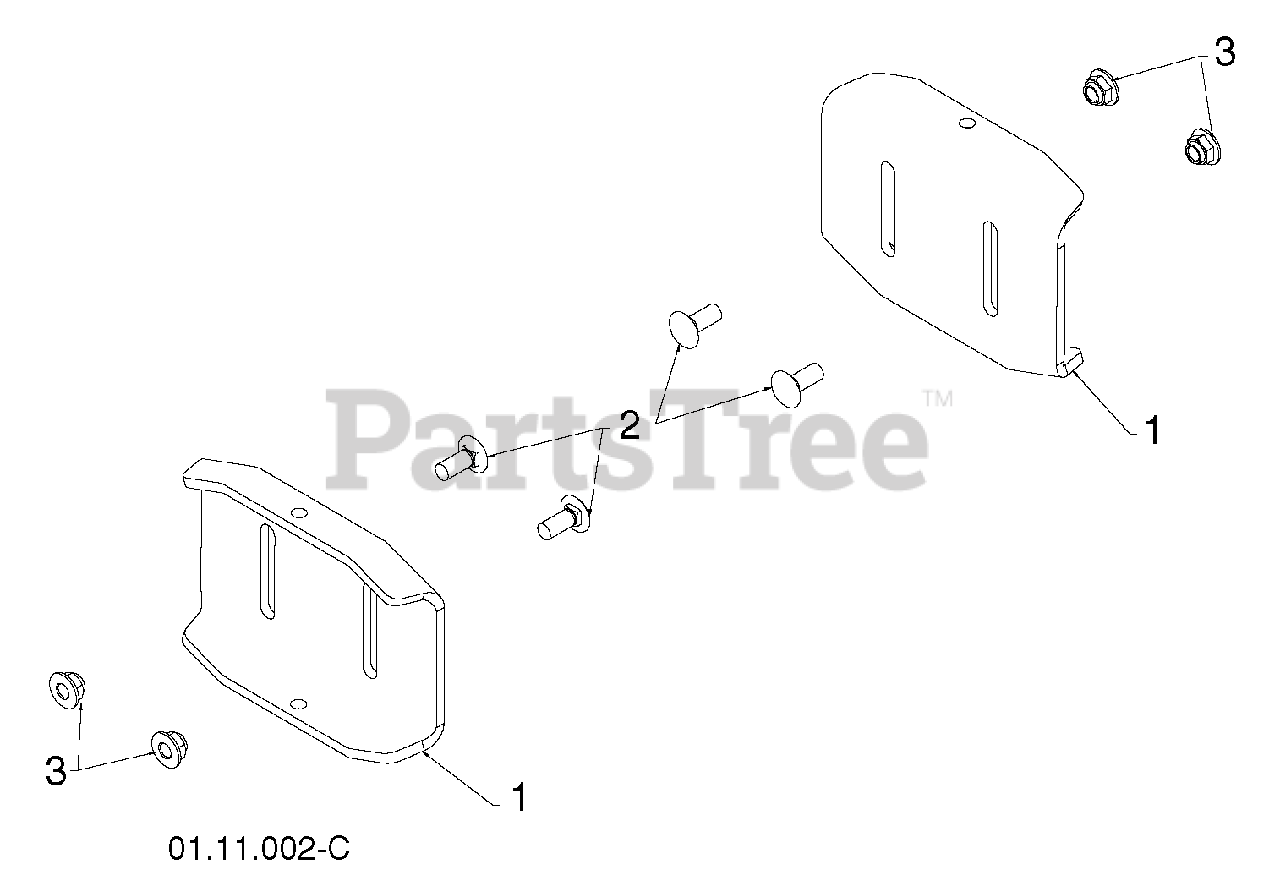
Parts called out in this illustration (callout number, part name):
1	SKID PLATE
2	BOLT
3	NUTNYLOK.FLRANGE.5/16-18
